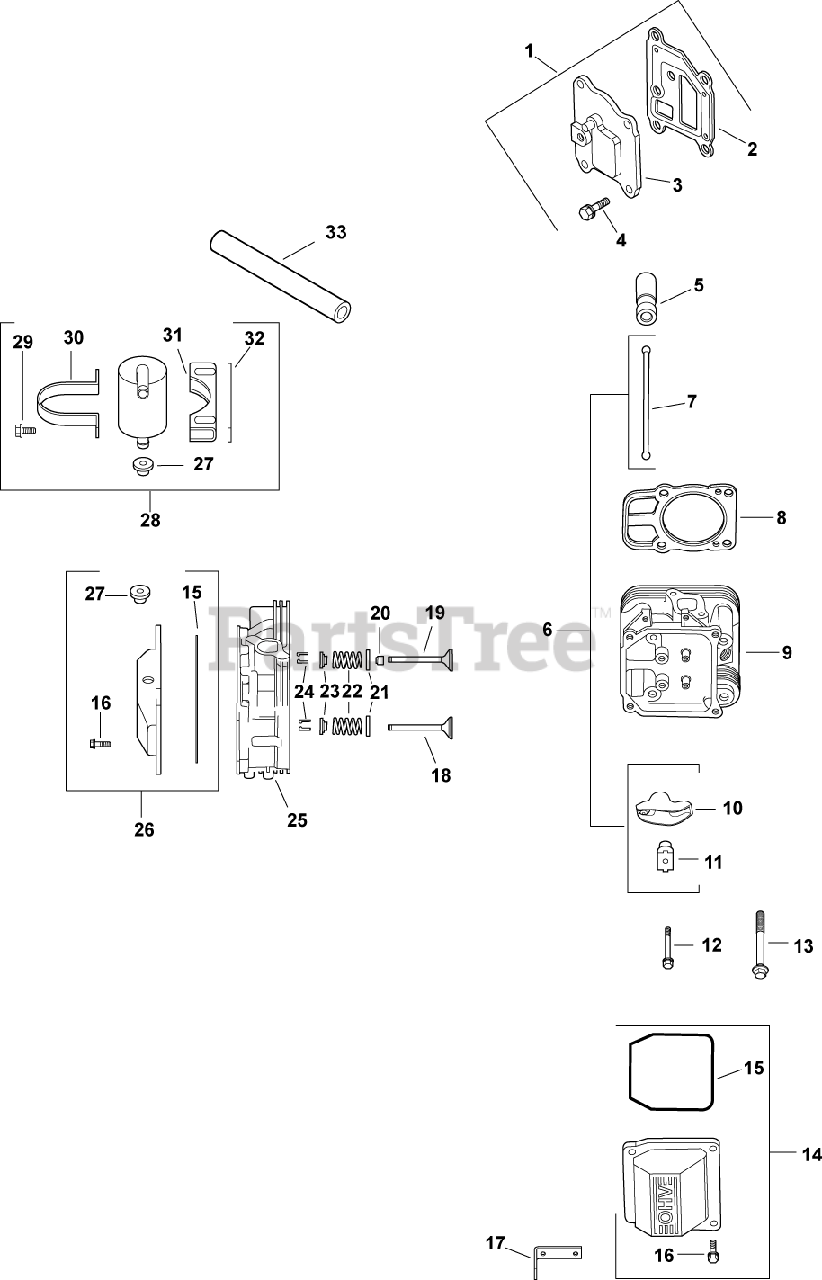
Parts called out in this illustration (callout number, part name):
1	KIT, BREATHER COVER W/GASKET
2	GASKET, BREATHER-USE 24 041 67-S
3	COVER, BREATHER -USE 24 096 125-S
4	SCREW,FLG THD FRM M6X1.0X20-(#25086396S)
5	LIFTER, HYDRAULIC VALVE-USE 25 351 10-S
6	KIT, VALVE TRAIN
7	ROD, PUSH
8	KIT, CYL HEAD GASKET (C17-22)
9	HEAD, ASSEM CYLINDER #2 -USE 24 318 113-
10	ARM, ROCKER
11	PIVOT, ROCKER ARM
12	SCREW, FLG M6X1.0X34
13	SCREW - USE 62 086 08-S
14	KIT, VALVE COVER-PLAIN
15	O-RING (YELLOW), VALVE COVER
16	SCREW, FLG M6X1.0X30
17	STRAP, LIFTING-USE 25 445 03-S
18	VALVE, EXHAUST (STD) - USE 32 016 01-S
19	VALVE, INTAKE (STD)
20	SEAL, VALVE STEM - (#2503214S)
21	RETAINER, SPRING
22	SPRING, VALVE
23	RETAINER, VALVE SPRING - USE 25 173 28-S
24	KIT, RETAINER
25	HEAD, ASSEM CYLINDER #1 -USE 24 318 105-
26	KIT, VALVE COVER
27	GROMMET, RUBBER
28	KIT, BREATHR SEPARATR-(#24755241S)
29	SCREW,FLG THD FRM M5X0.8X16-(#25086398S)
30	STRAP, BREATHER - USE 24 755 241-S
31	BRACKET, BREATHER SEPARATOR
32	SPACER
33	HOSE, BREATHER
2401602-S	VALVE, EXHAUST (.25)
2401702-S	VALVE, INTAKE (.25)
2432686-S	HOSE, BREATHER
2432687-S	HOSE, BREATHER
